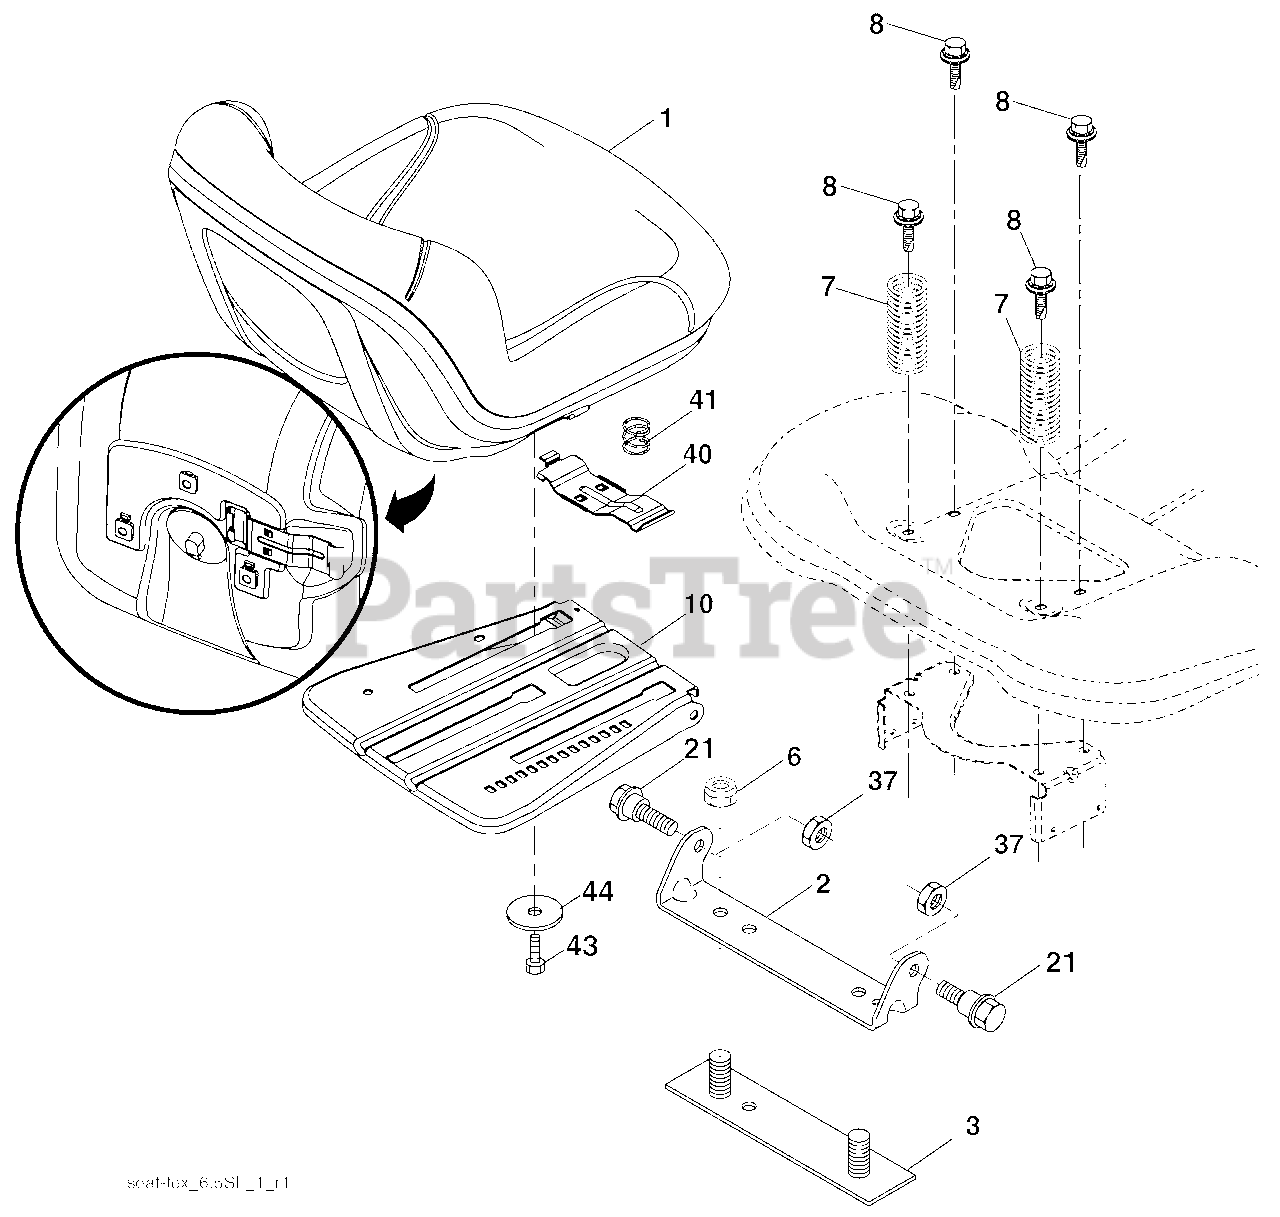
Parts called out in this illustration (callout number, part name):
1	Seat
2	Bracket Pivot Fender
3	Strap, Asm Fender
6	Nut, Lock w/Ins. 3/8-16 unc
7	Spring, Seat Cprsn
8	Bolt 5/16-18 unc x 3/4 w/Sems
10	Pan, Seat
21	Bolt, Shoulder 5/16-18
37	Nut, Lock 5/16-18 unc
40	Handle Slide Seat
41	Spring Latch Seat
43	Bolt Fin Hex 3/8-16 unc x 3/4
44	Washer 13/32 x 2-3/8 x 12 Ga.
